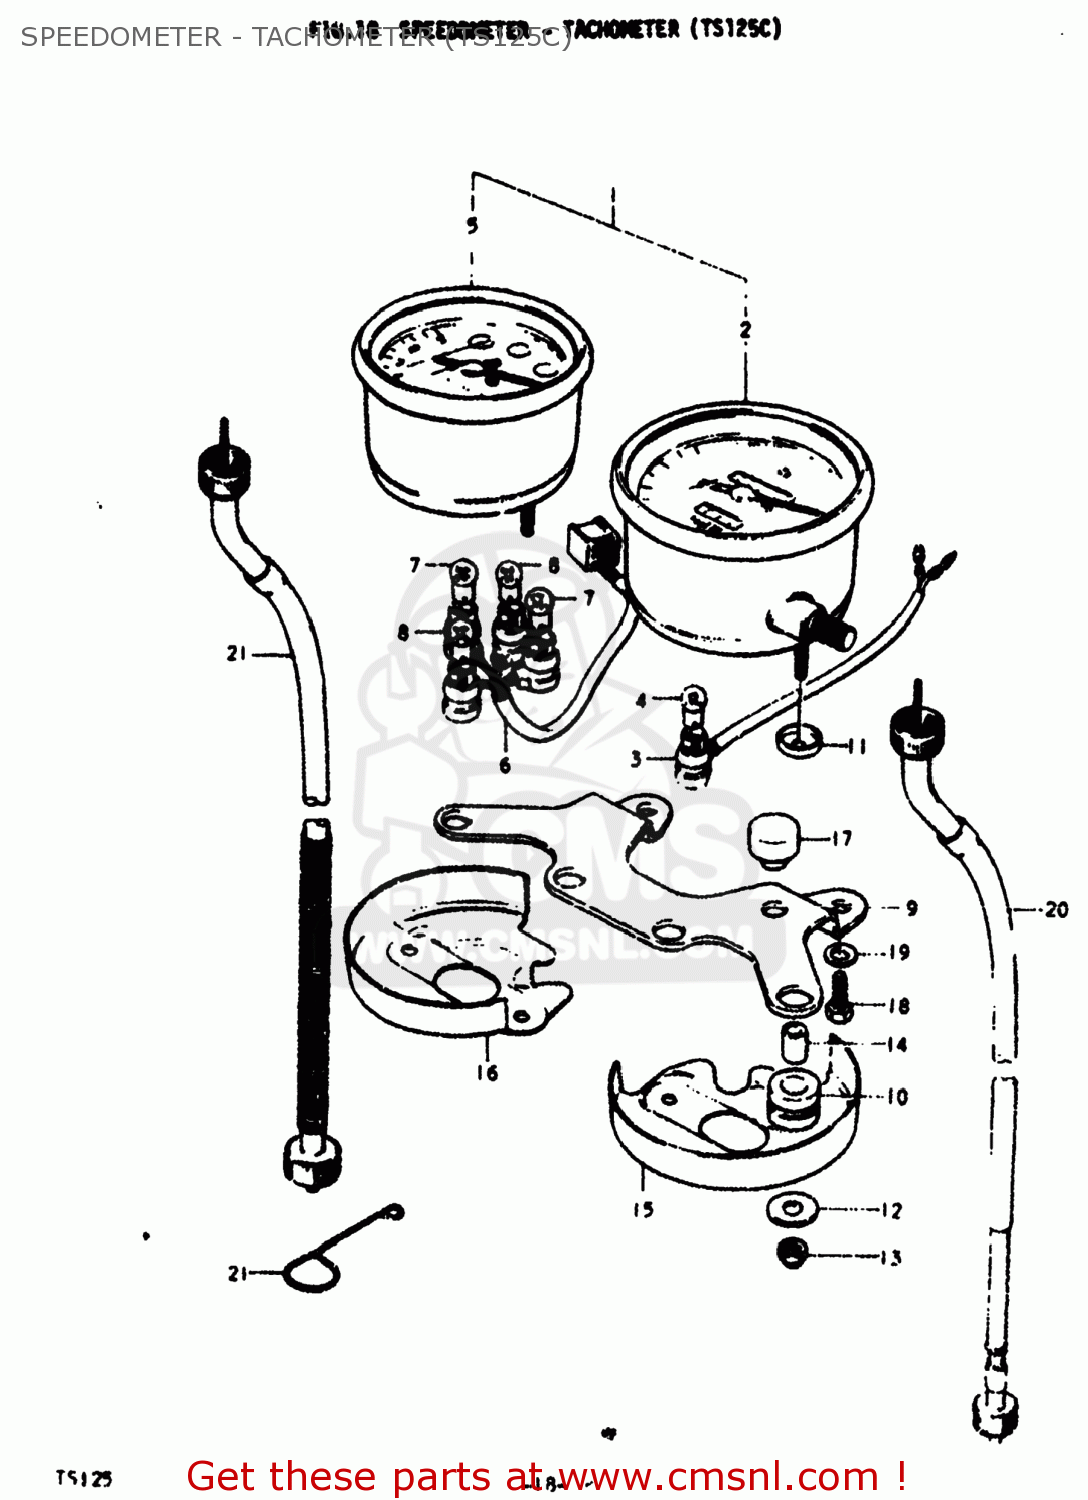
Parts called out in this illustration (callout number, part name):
1	SPEEDOMETER ASSEMBLY
2	SPEEDOMETER ASSEMBLY
3	SOCKET,SPEEDOMETER
4	BULB(6V1.7W,STANLEY,A61A)
5	METER,TACHOMETER
6	SOCKET,TACHOMETER
7	BULB(6V1.7W,STANLEY,A61A)
8	BULB(6V/3W)
9	BRACKET,COMBINATION METER
10	CUSHION,METER
11	WASHER
12	WASHER,METER
13	NUT
14	SPACER,SPEEDOMETER
15	COVER
16	PLATE,TACHOMETER UNDER
17	CUSHION,METER
18	BOLT, UPPER
19	WASHER
20	CABLE ASSEMBLY,SPEEDOMETER
21	CABLE ASSEMBLY,TACHOMETER
22	GUIDE,TACHOMETER CABLE
